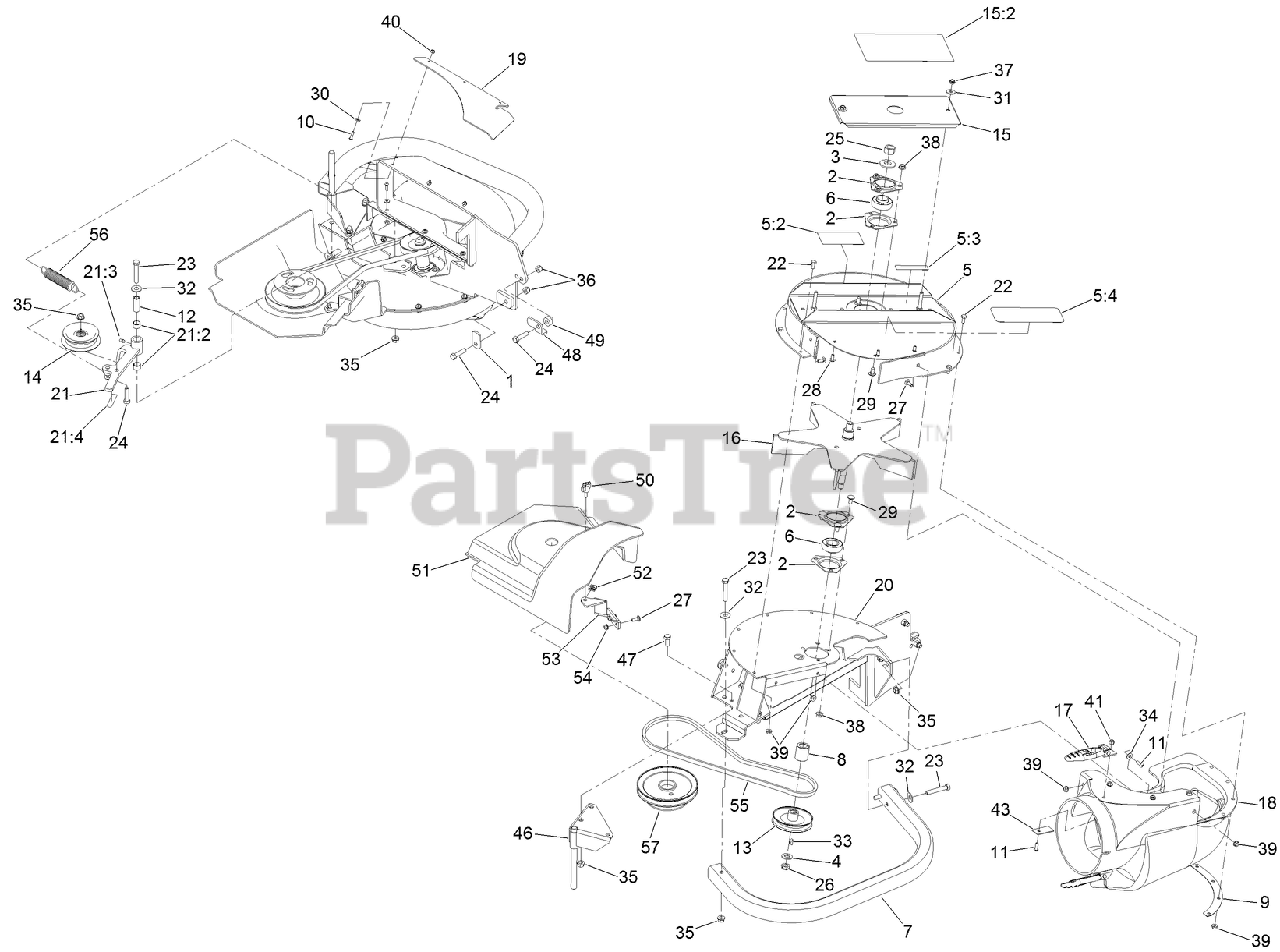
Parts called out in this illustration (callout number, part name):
1	LATCH-CATCHER, GRASS
2	HOUSING-FLANGE
3	WASHER-SPRING
4	WASHER-FLAT
5	UPPER HOUSING ASM
5:2	DECAL-WARNING
5:3	DECAL-COVER, MISSING
6	BEARING
8	SPACER
9	PLATE-BACKING, BLOWER
10	SCREW-HSBH
11	SCREW-HSBH
12	BUSHING
13	SHEAVE
14	IDLER-FLAT
15	COVER-BEARING
15:2	Decal, Warning
16	IMPELLER
17	LATCH-RUBBER
18	CHUTE-BLOWER
19	PLATE-BOTTOM
20	MOUNT-BLOWER
21	IDLER ARM ASM
21:2	BUSHING
21:3	FITTING-GREASE
21:4	DECAL-WARNING
22	SCREW-HH
23	SCREW-HH
24	SCREW-HH
25	NUT-HEX
26	NUT-LOCK, NI
27	BOLT-CARR
28	SCREW-CARR
29	SCREW-CARR
30	WASHER-FLAT
31	WASHER-FLAT
32	WASHER-FLAT
33	KEY-WOODRUFF
34	WASHER-FLAT
35	NUT-HHF, WHIZ
36	NUT-LOCK, NI
37	NUT-LOCK, NI
38	NUT-HF
39	NUT-HF
40	NUT-LOCK, NI
41	NUT-LOCK, NI
43	PLATE-BACKING
46	PIN-MOUNT
47	SCREW-HH
48	LATCH-STOP
49	SPACER
51	SHIELD-BELT, 72IN
52	NUT-SPEED
53	BRACKET-COVER, BELT (60/72)
54	NUT-HF
55	BELT-V
56	SPRING-EXTENSION
57	PULLEY-BLOWER
